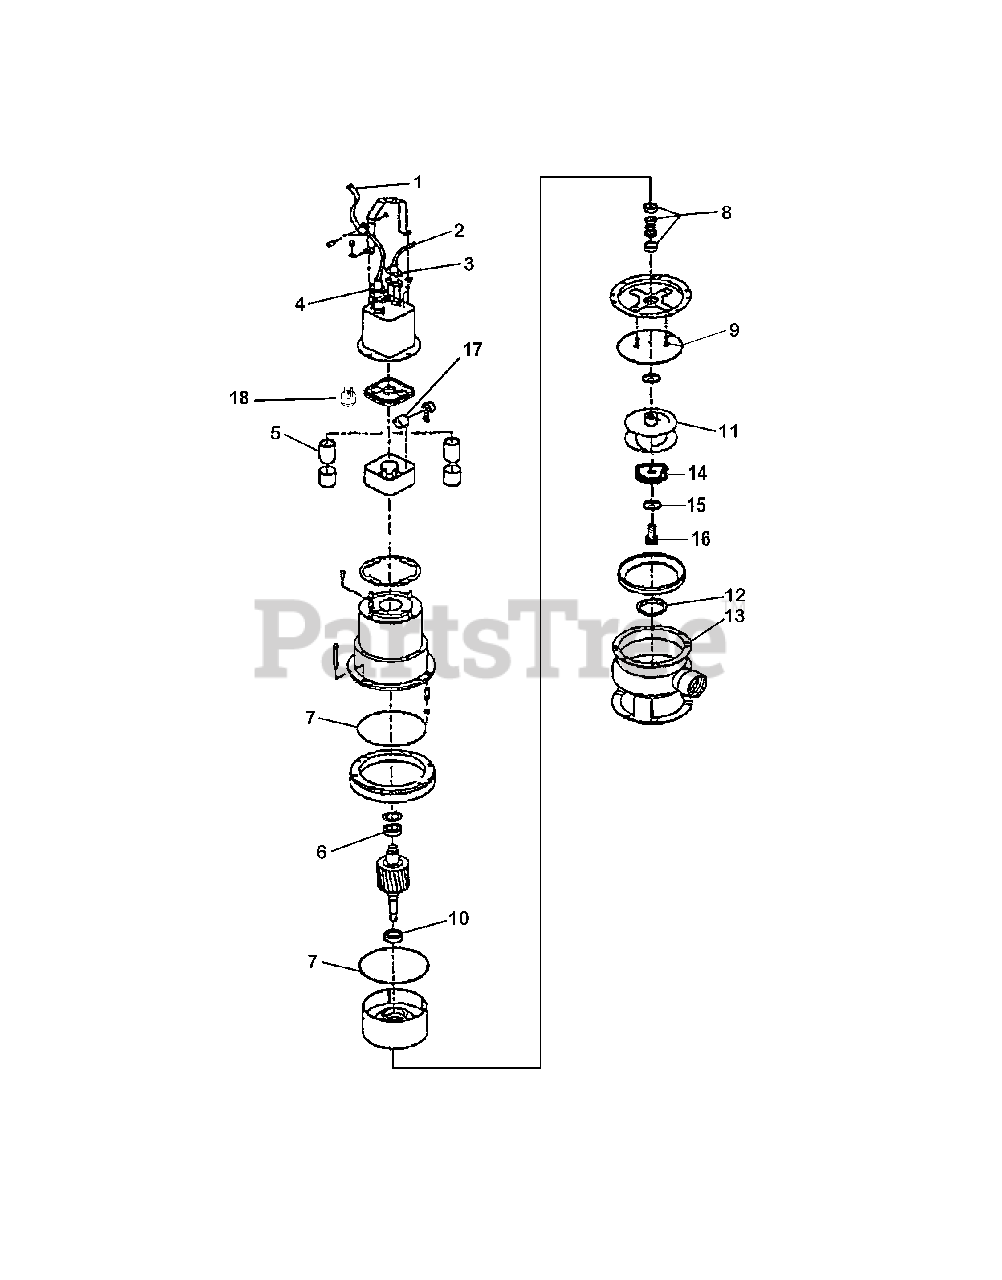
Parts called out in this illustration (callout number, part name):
1	SWITCH, FLOAT
2	WIRE, POWER
3	CONNECT WIRE
4	GROMMET, CABLE
5	CAPACITOR
6	BEARING (UPPER)
8	SEAL KIT
10	BEARING (LOWER)
11	IMPELLER
12	RING, CASING
15	WASHER, LOCK
17	PROTECTOR, THERMAL
18	PROTECTOR, THERMAL
